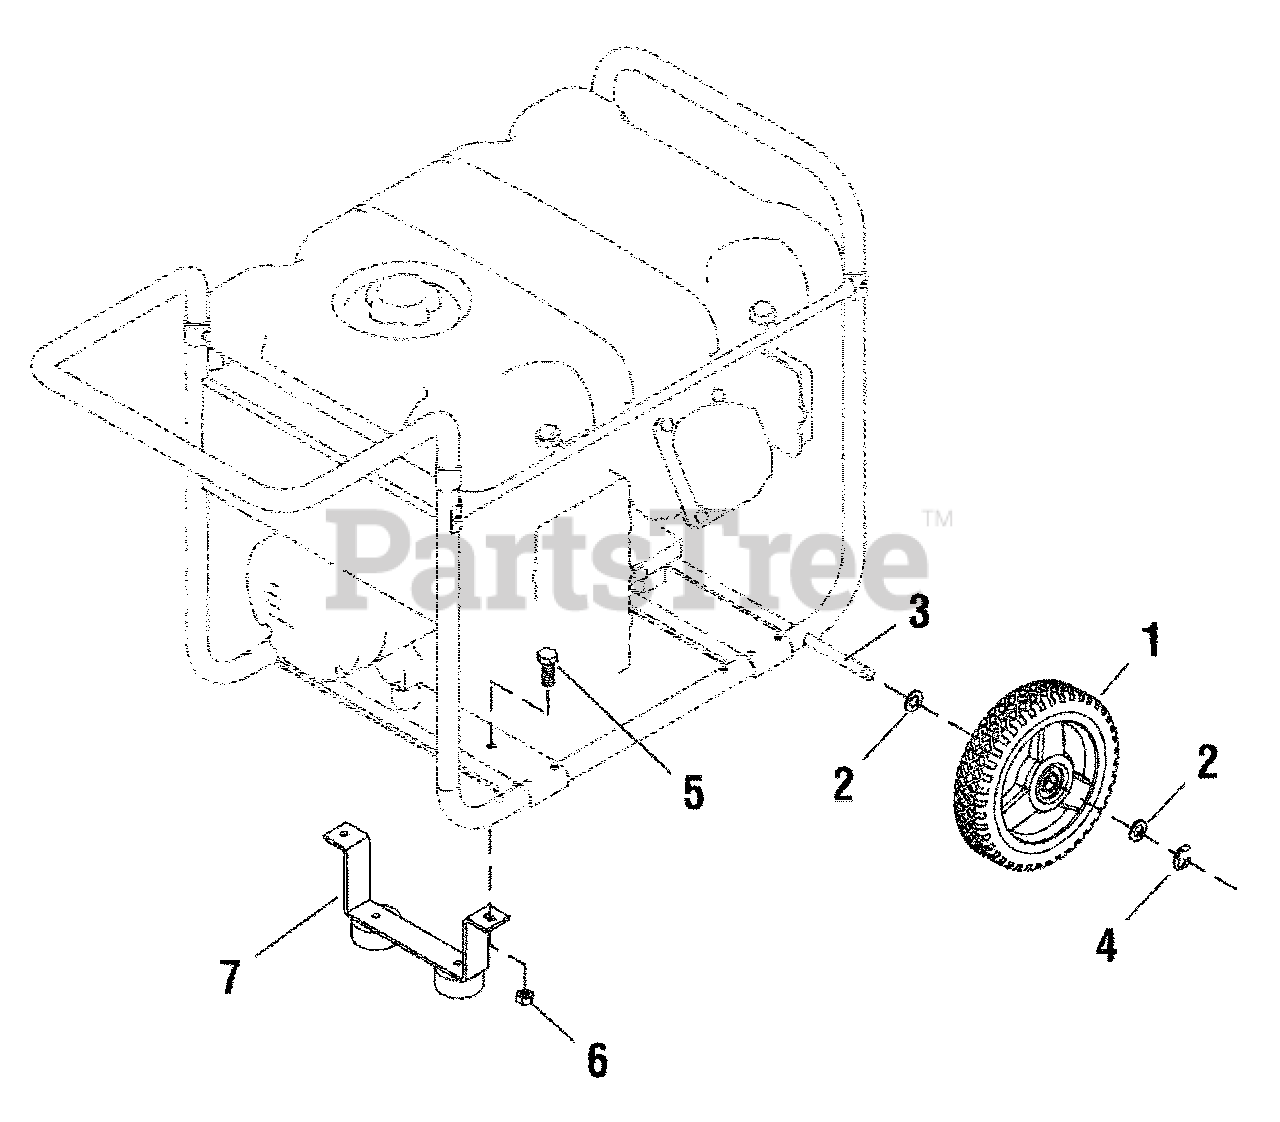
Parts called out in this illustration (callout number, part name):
2	* WASHER, 1/2
3	AXLE
4	E-RING
5	* CAPSCREW, Hex Head, M8 1.25 x 20
